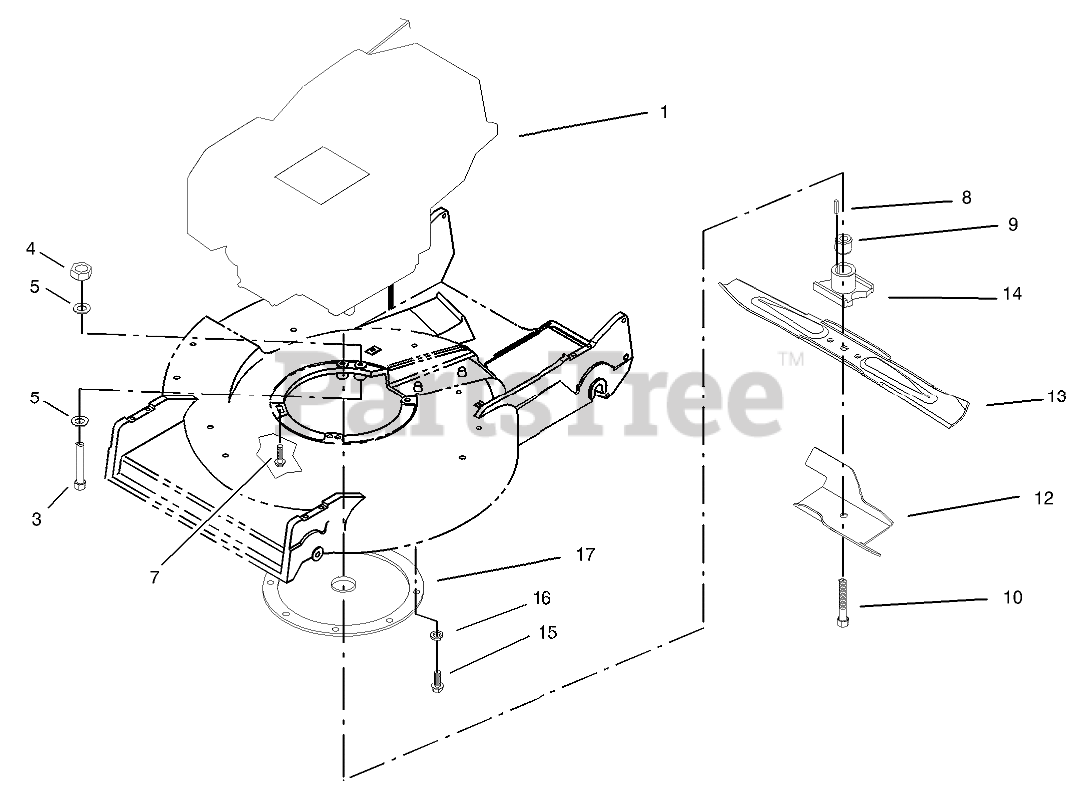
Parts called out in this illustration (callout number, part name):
1	ENGINE-HONDA, GXV 160K1A1T
3	SCREW-HH
4	NUT-LOCK, NI
5	WASHER-PLAIN
7	SCREW-SHOULDER
8	KEY-SQUARE
9	Spacer-Retainer, Blade
10	BOLT-BLADE
12	STIFFENER-BLADE
13	Blade
14	RETAINER-BLADE
15	SCREW-HWHTF
16	WASHER-LOCK, INTERNAL
17	PROTECTOR-CRANKSHAFT
